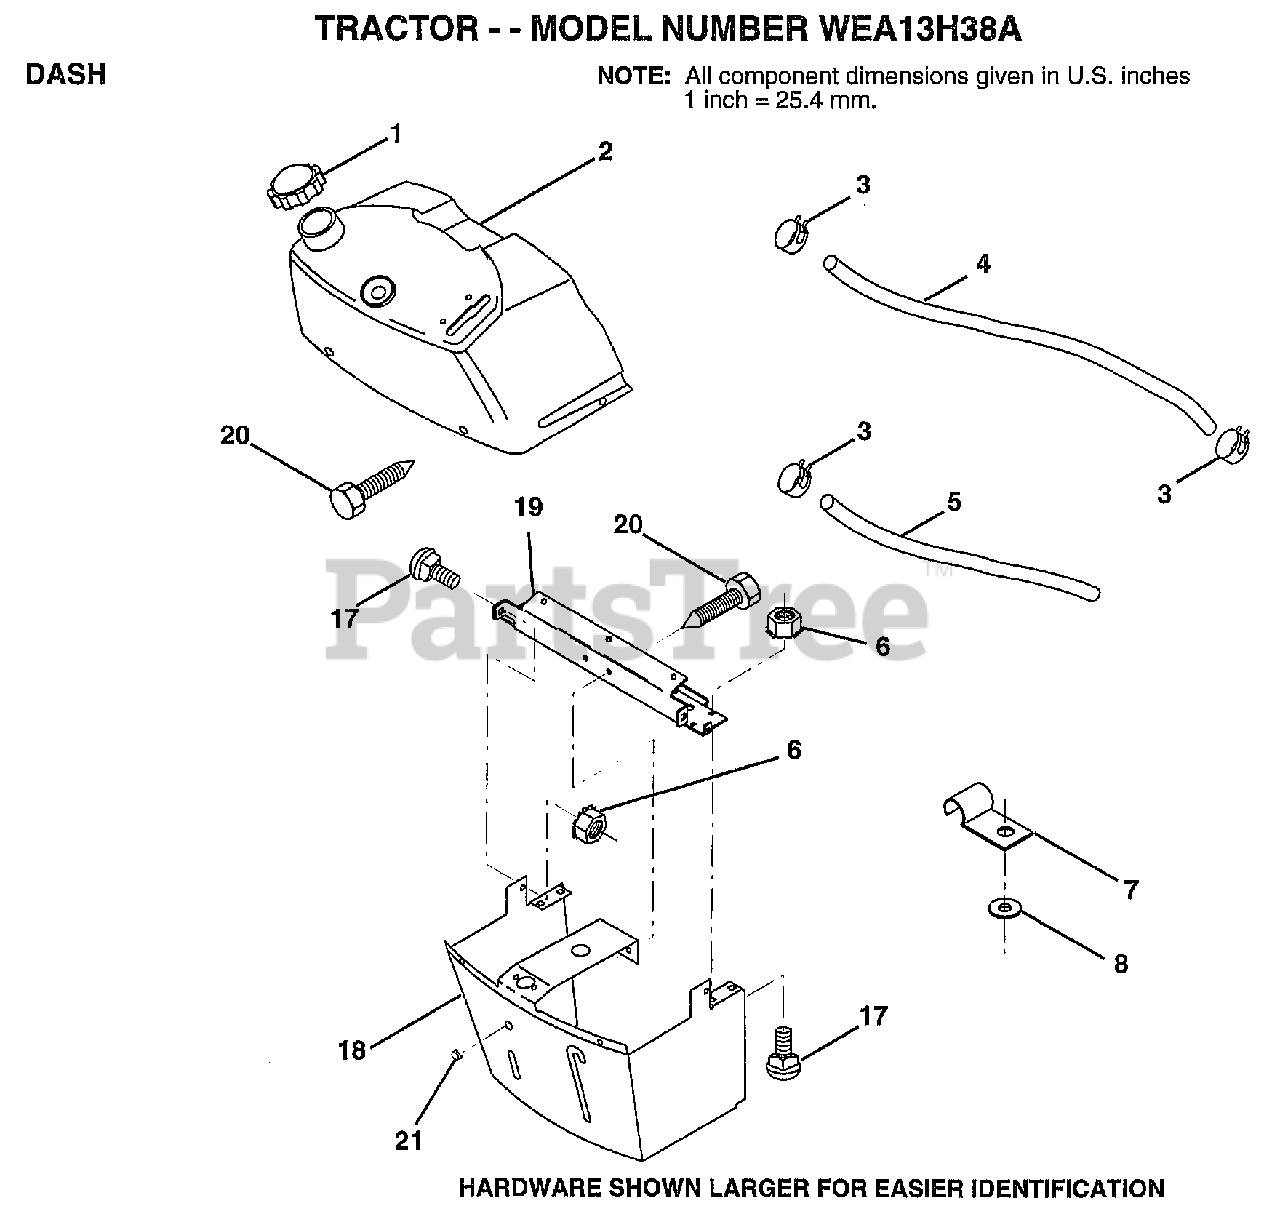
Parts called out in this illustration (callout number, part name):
1	CAP BLK FUEL LR
2	TANK.ASM.DASH.LR
3	HOSE CLAMP
4	LINE, FUEL
5	LINE, FUEL
6	NUT HXKEP 1/4X20
7	CLIP T
8	WASHER PM
17	BOLT
18	SUPT ASM DASH
19	CROSS BRACE
20	SCREW.1/4-20X1/2
21	PLUG DOME
